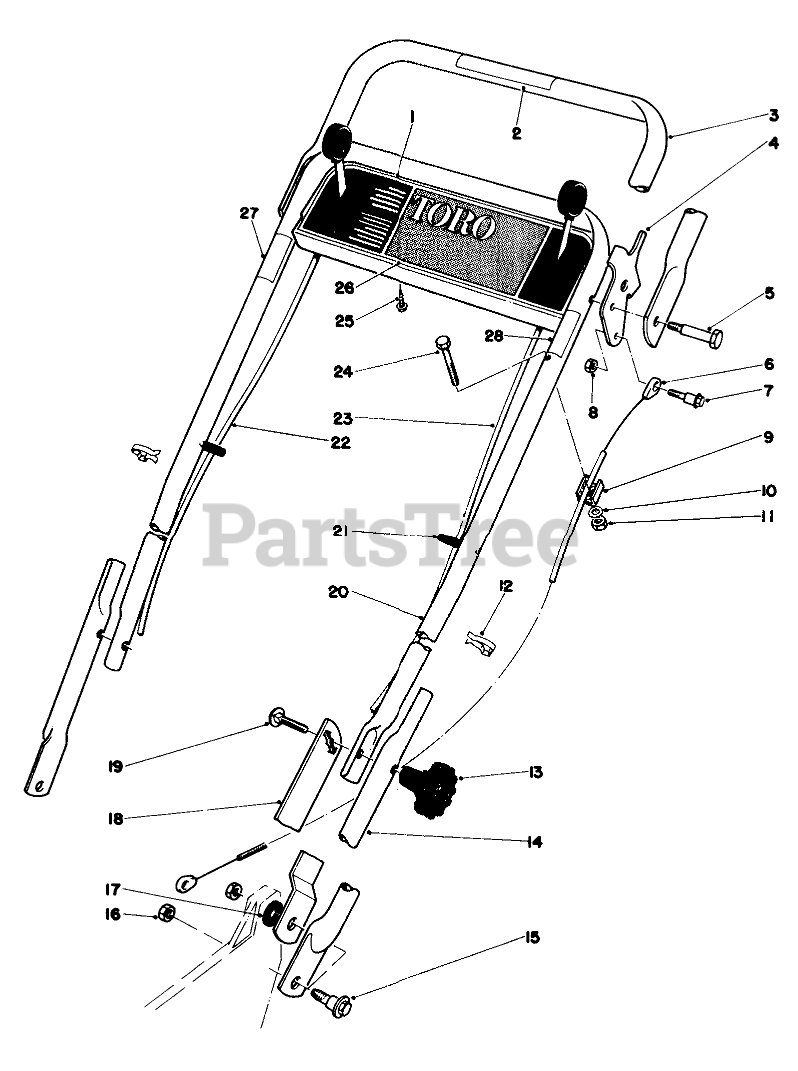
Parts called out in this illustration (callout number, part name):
1	Control Panel
2	Decal-Traction Control (German)
3	Demand Handle
4	Demand Handle Stop
5	BOLT-SHOULDER
6	DEMAND HANDLE CABLE
7	Shoulder Bolt
8	NUT-HEX, SIDE DEFORM
9	CLAMP-CABLE
10	WASHER-FLAT
14	LOWER HANDLE
15	SCREW-SHOULDER
16	Nut
17	SPACER
18	Handle Latch L.H.
19	SCREW-CARR
20	Upper Handle
21	Cap Vinyl
22	Ground Speed Control
23	Throttle Control
24	SCREW-HH
25	SCREW-HWHTF
26	Decal-Control Panel (German)
27	Decal-Control Shift (German)
28	Decal-Throttle
